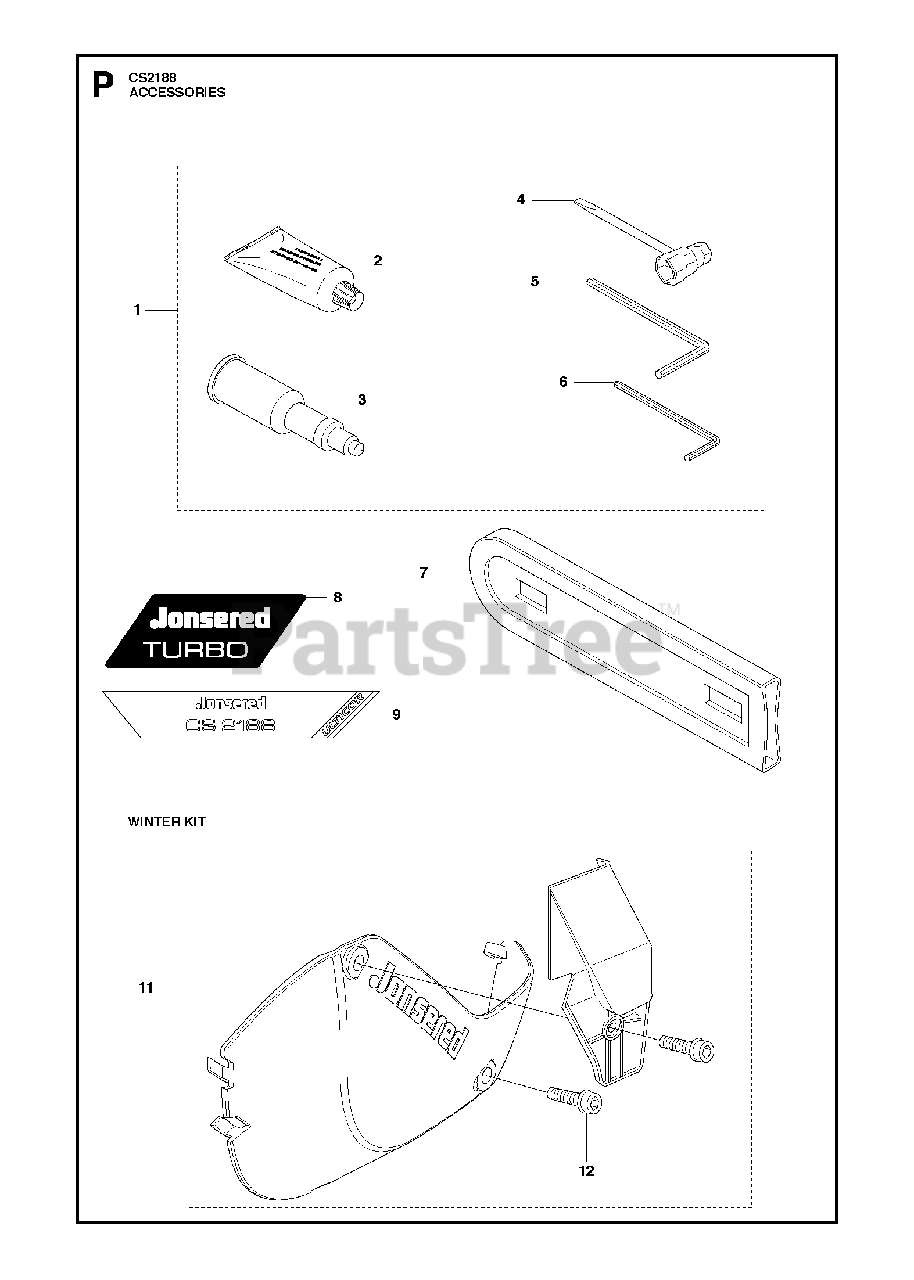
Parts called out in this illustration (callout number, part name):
2	GREASE
3	GREASE GUN
5	L-SPANNER
6	L-SPANNER
7	BAR COVER
8	DECAL
9	LABEL
11	PROTECTOR
12	SCREW
